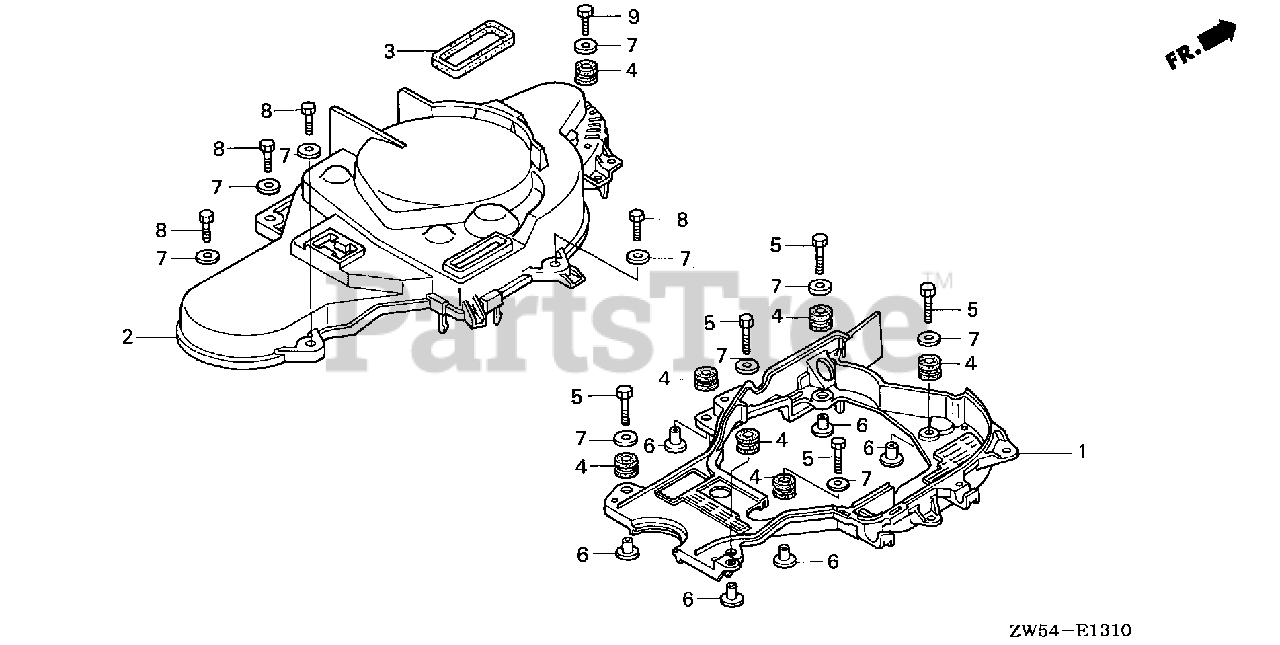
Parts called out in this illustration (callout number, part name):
1	COVER, TIMING BELT (LOWER)
2	COVER, TIMING BELT (UPPER)
3	RUBBER, SEAL
4	GROMMET, CASE (LOWER)
5	BOLT, FLANGE (6X25)
6	COLLAR, MODULE IGNITION CONTROL CASE (CDI)
7	WASHER, PLAIN (6MM)
8	BOLT, FLANGE (6X20)
9	BOLT, FLANGE (6X22)
